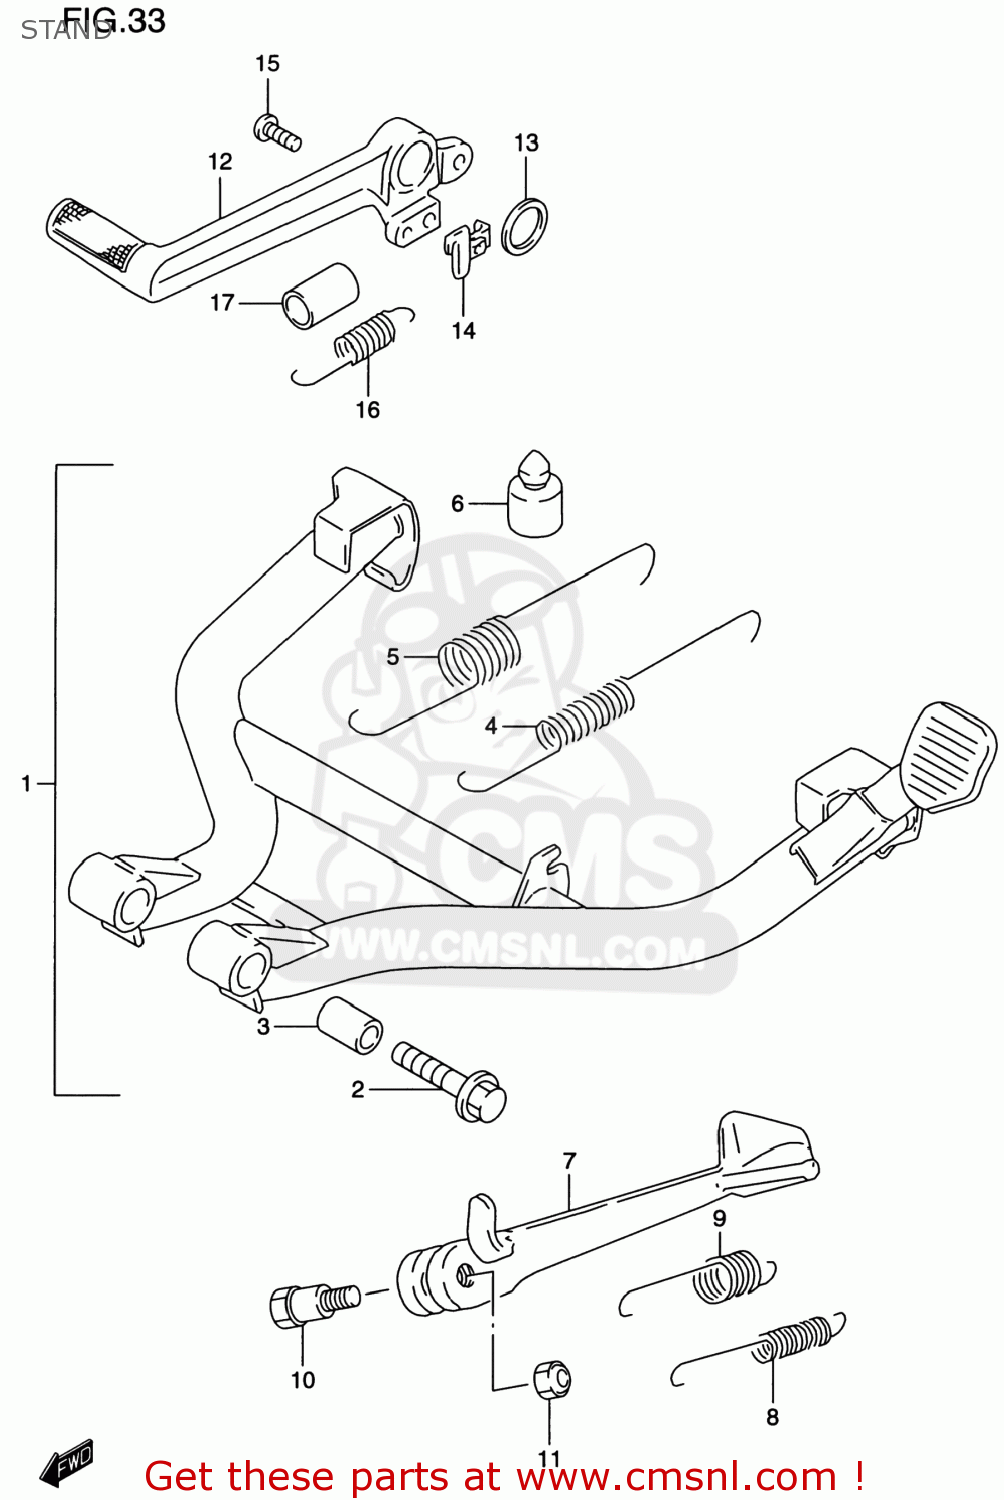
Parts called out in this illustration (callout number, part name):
1	STAND SET,CTR
2	BOLT(10X48)
3	SPACER(10X16X25.5)
4	SPRING
5	SPRING OUTER
6	CUSHION
7	STAND,PROP
8	SPRING
9	SPRING
10	BOLT(10X34)
11	NUT
12	PEDAL,BRAKE
13	WASHER(18X24X1)
14	BRACKET,STOP LAMP SWITCH SPR
15	SCREW
16	SPRING
17	TUBE,BRAKE SPRING GUIDE
